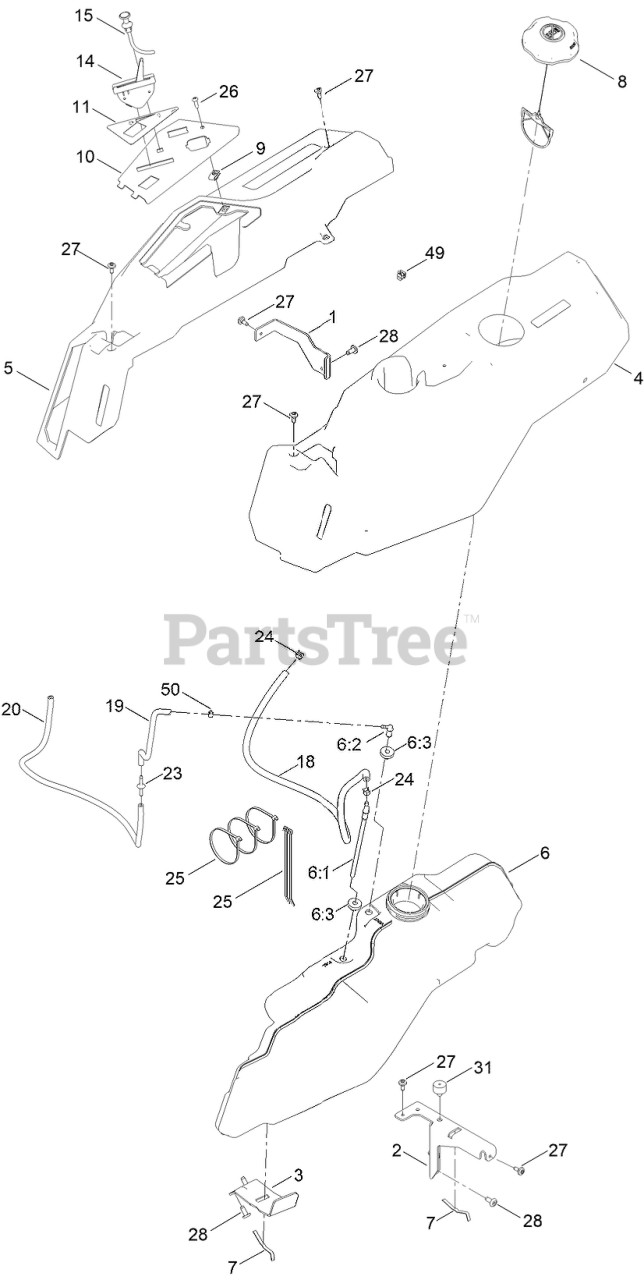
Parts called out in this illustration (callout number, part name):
1	BRACKET-POD
2	SUPPORT-POD, LH
3	SUPPORT-TANK, FUEL
4	POD-LH
5	POD-RH, MYRIDE
6	TANK-FUEL ASM
6:1	CONNECTOR-ELBOW, 90 DEG
6:2	FITTING-ELBOW 90
6:3	BUSHING
7	SPRING
8	CAP-FUEL, RATCHETING
10	PANEL - CONTROL
11	DECAL-PANEL CONTROL
14	CABLE-THROTTLE
15	CABLE-CHOKE
18	HOSE-FUEL
19	HOSE-FUEL
20	HOSE-FUEL
23	ADAPTER ORIFICE
24	CLAMP-HOSE
25	TIE-CABLE
26	SCREW-PRH
27	SCREW-SHOULDER
31	BUMPER-GROMMET
49	CLIP-HARNESS
50	CLAMP-HOSE
